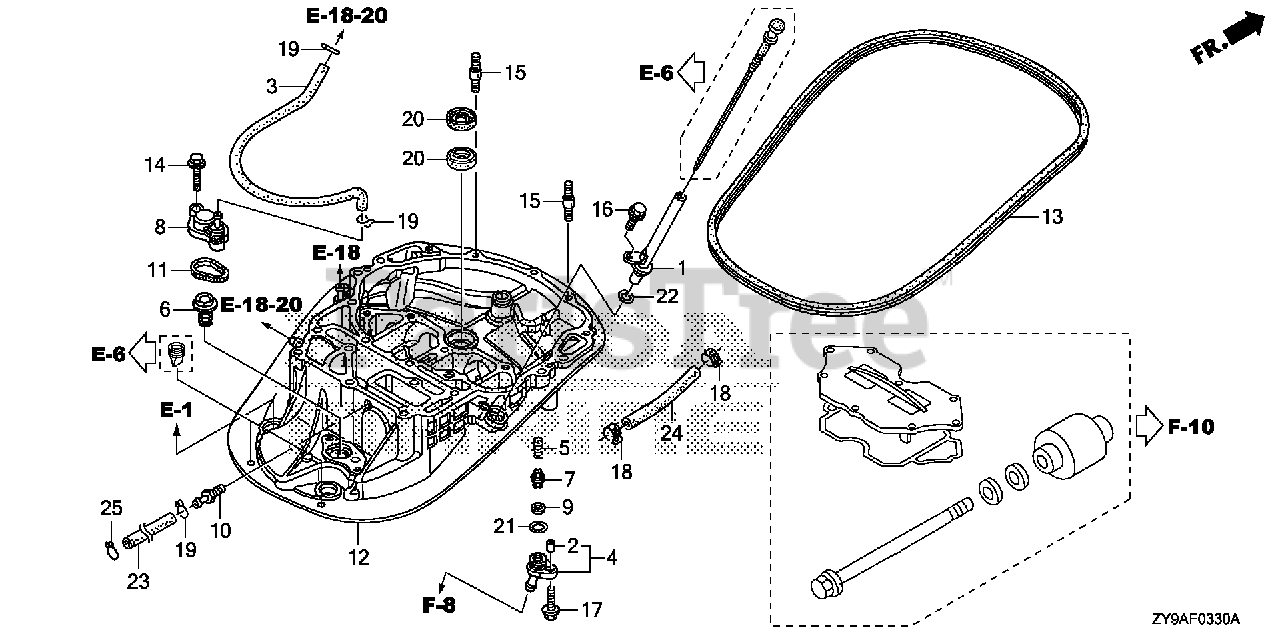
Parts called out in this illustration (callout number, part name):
1	PIPE, OIL LEVEL
2	COLLAR, DISTANCE (6.5X11X7.5)
3	TUBE B, WATER
4	COVER, FLUSH VALVE
5	SPRING, FLUSH VALVE
6	VALVE ASSY., RELIEF
7	VALVE, FLUSH
8	COVER, RELIEF VALVE
9	GASKET, FLUSH VALVE
10	JOINT, WATER TUBE
11	O-RING, THERMOSTAT COVER
12	CASE, MOUNT *NH8* (DARK GRAY)
13	SEAL A, COVER (LOWER)
14	BOLT, FLANGE (6X22)
15	BOLT, STUD (8X28)
16	BOLT, FLANGE (6X12)
17	BOLT, FLANGE (6X20) (ENGINE NO.)
18	CLAMP, TUBE (D10.5) (ENGINE NO.)
19	CLIP, TUBE (B10)
20	SEAL, WATER (22X35X7)
21	O-RING (16MM)
22	O-RING (11.5X3.5)
23	TUBE, WATER CHECK
24	BULK HOSE, VACUUM (7X3000) (7X550)
25	CLIP, TUBE
